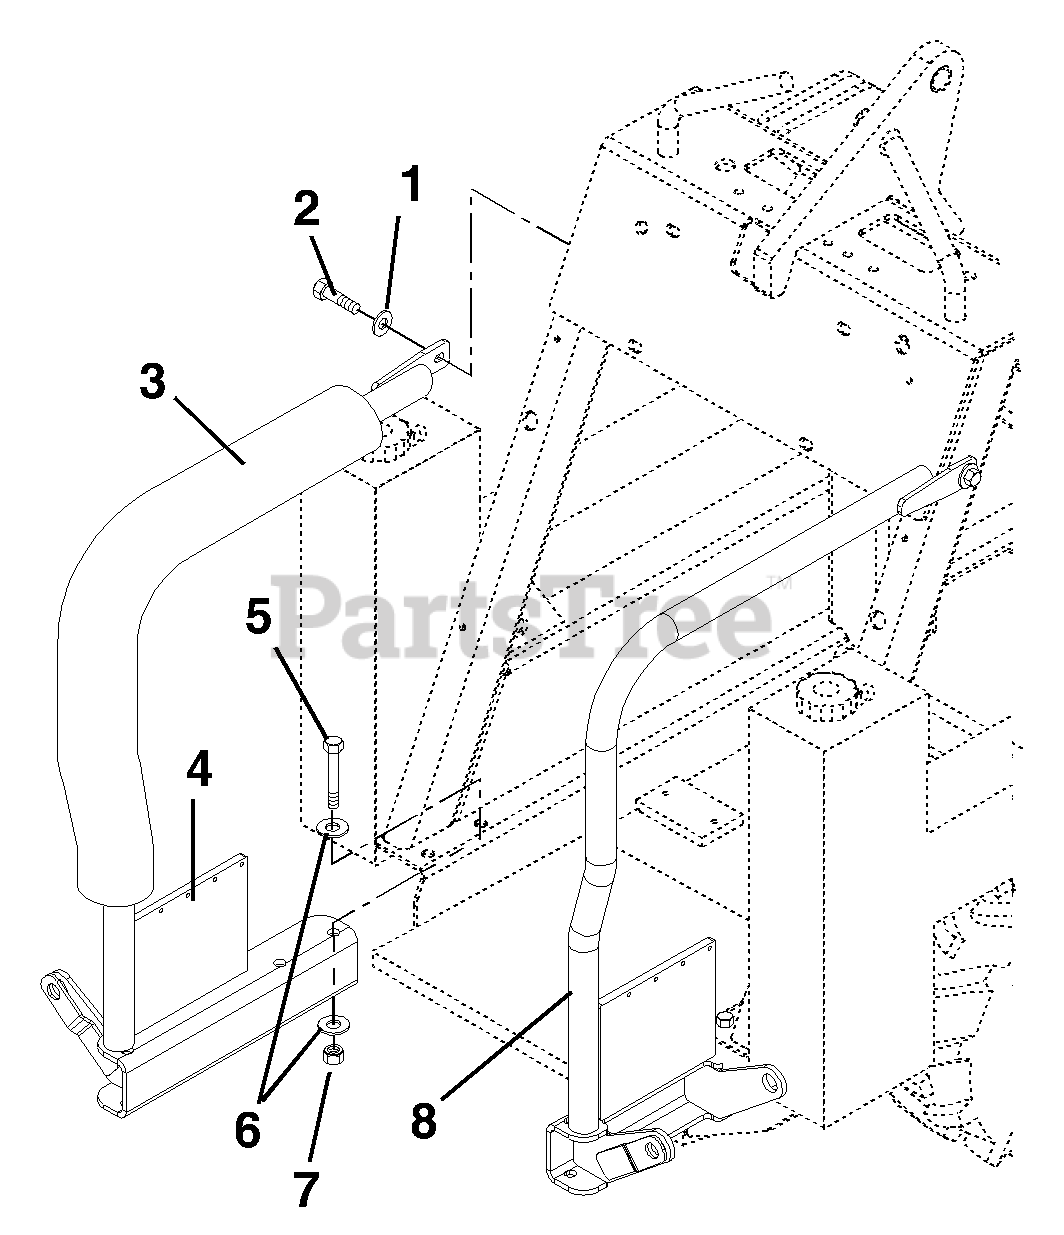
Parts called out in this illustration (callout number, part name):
1	Washer-Flat-Steel .38 x .875 x .083
2	Bolt, Hex 13 mm M8-1.25 x 16
3	Foam, 36" long
4	Weldment, Weight- Left Hand
5	Bolt, Hex 19mm M12-1.75 x 110
6	Washer-Flat-Steel .531 x 1.06 x .095
7	Nut, hex 19mm M12-1.75 nyloc
8	Weldment, Weight- Right Hand
